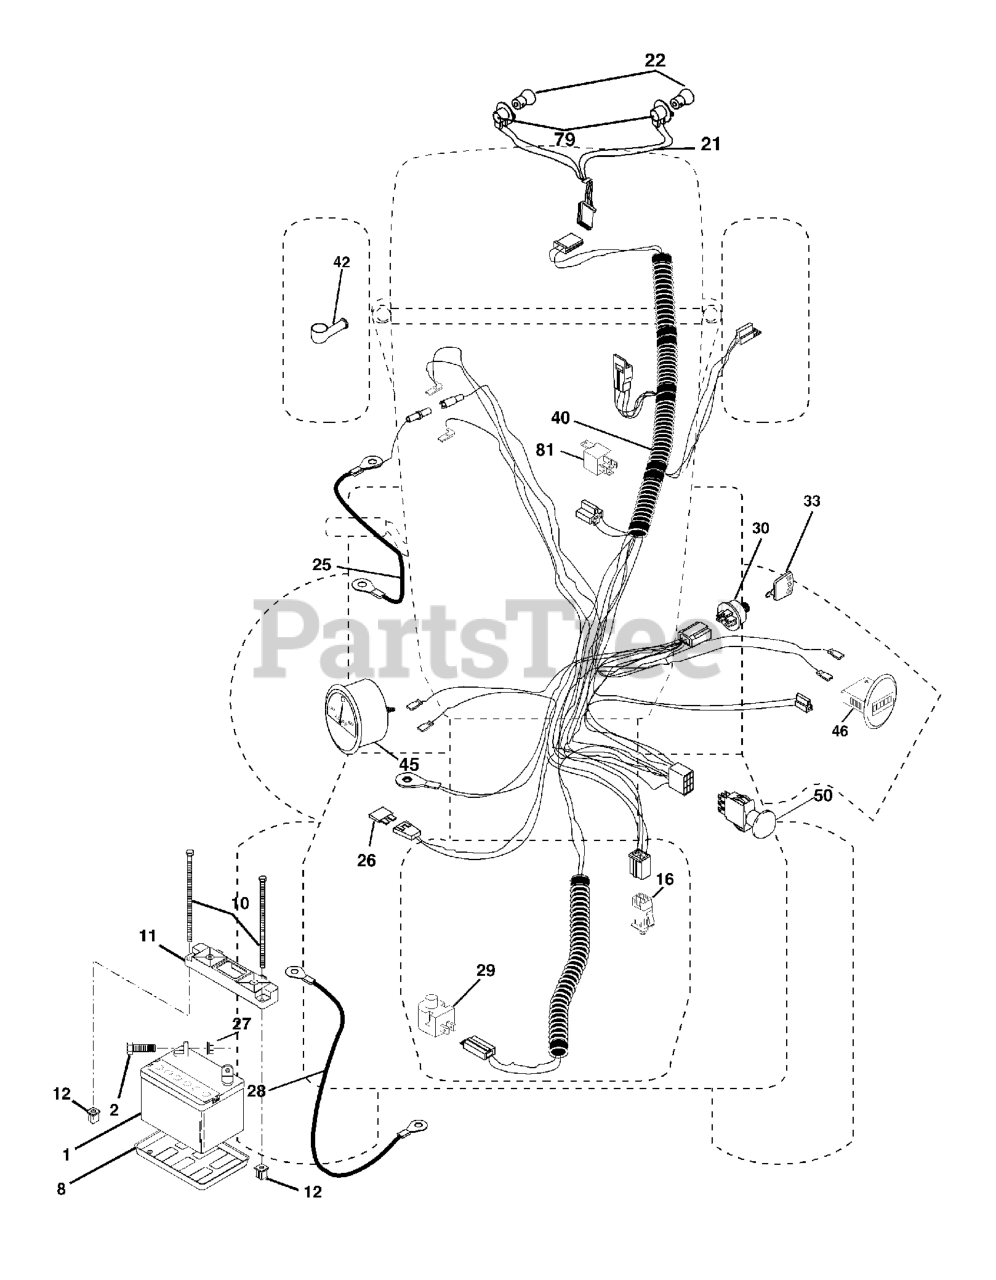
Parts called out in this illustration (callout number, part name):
1	BATTERY 12V .35 AMP
2	BOLT.HEX.1/4.X.3/4.DICHROMATE
8	BATTERY TRAY T
10	BOLT 1/4-20 X 7.5
11	BATTERY HOLDDOWN FRONT MOUNT
12	NUT, PUSH NYLON 1/4" BATTERY
16	SWITCH INTERLOOK PUSH-IN
21	HARNESS.W/LIGHT SOCKET
22	LIGHTBULB
25	CABLE.4GA.RED.W/16GA.RED.WIRE
26	FUSE HYT
27	NUT
28	CABLE, GROUND
29	RP.SWITCH.PLUNGER.NC.GRAY
30	IGNITION SWITCH
33	KEY MLD GEN DELTA
40	HARNESS.IGNITION.VGT.NO.RELAY
42	COVER.TERMINAL.RED
45	RP AMMETER.ROUND.SILVER.DELTA
46	RP HOURMETER SNAP-IN
50	RP.PTO.SWITCH.8 TERMINAL.BLACK
79	BULB HOLDER ASM.
81	RELAY.ASSY.T
